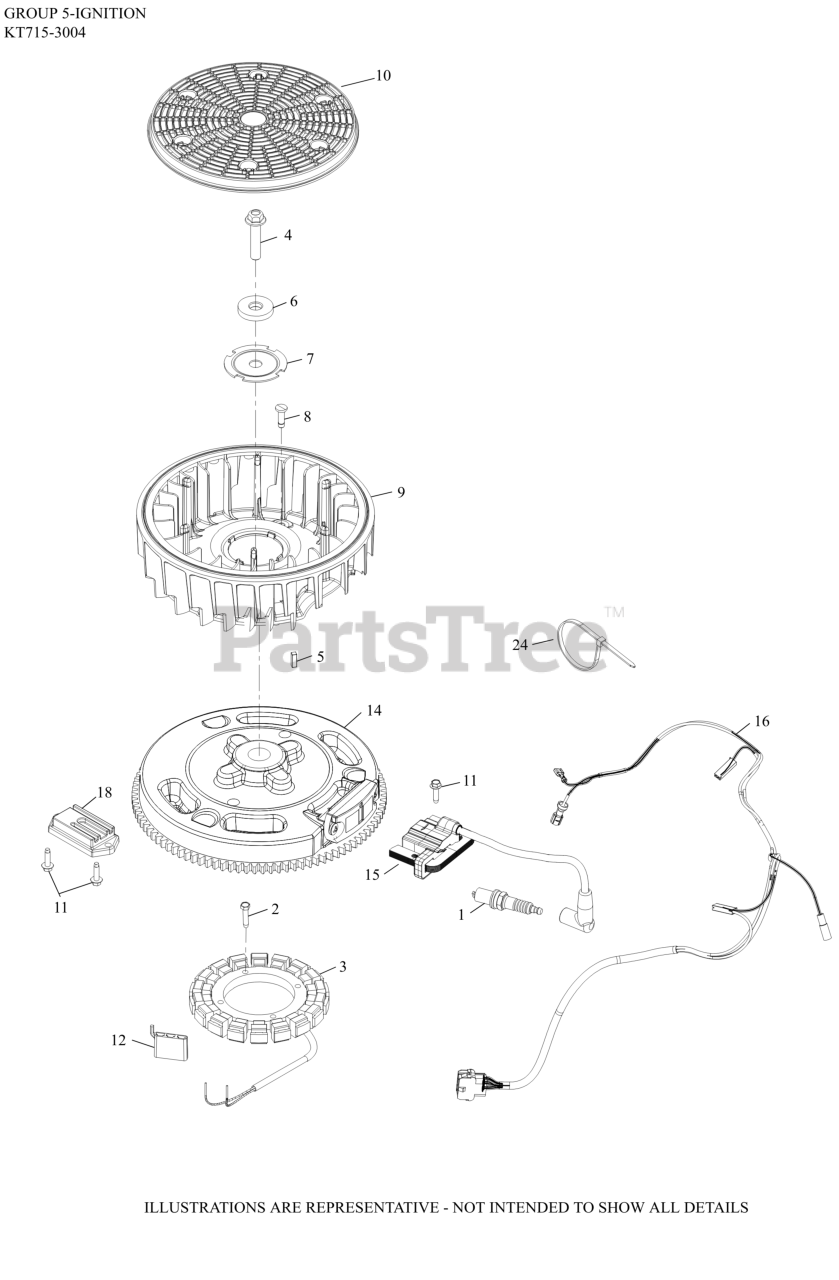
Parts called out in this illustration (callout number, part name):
1	SPARK PLUG, RFI
2	SCREW, THREAD FORMING
3	KIT, 15 / 20 AMP STATOR
4	SCREW, HEX FLANGE
5	KEY, SQUARE
6	WASHER, FLAT
7	PLATE, FAN MOUNTING
8	RETAINER, FLYWHEEL FAN
10	SCREEN, GRASS
11	SCREW, THD FRM-USE 25 086 473-S
12	CONNECTOR
14	FLYWHEEL ASSEMBLY
15	MODULE, CDI IGNITION
16	HARNESS ASSEMBLY-USE 32 176 53-S
16	HARNESS ASSEMBLY, (MECH AUTO-CHOKE)
18	REGULATOR/RECTIFIER 12/15A HALF-WAVE STD
